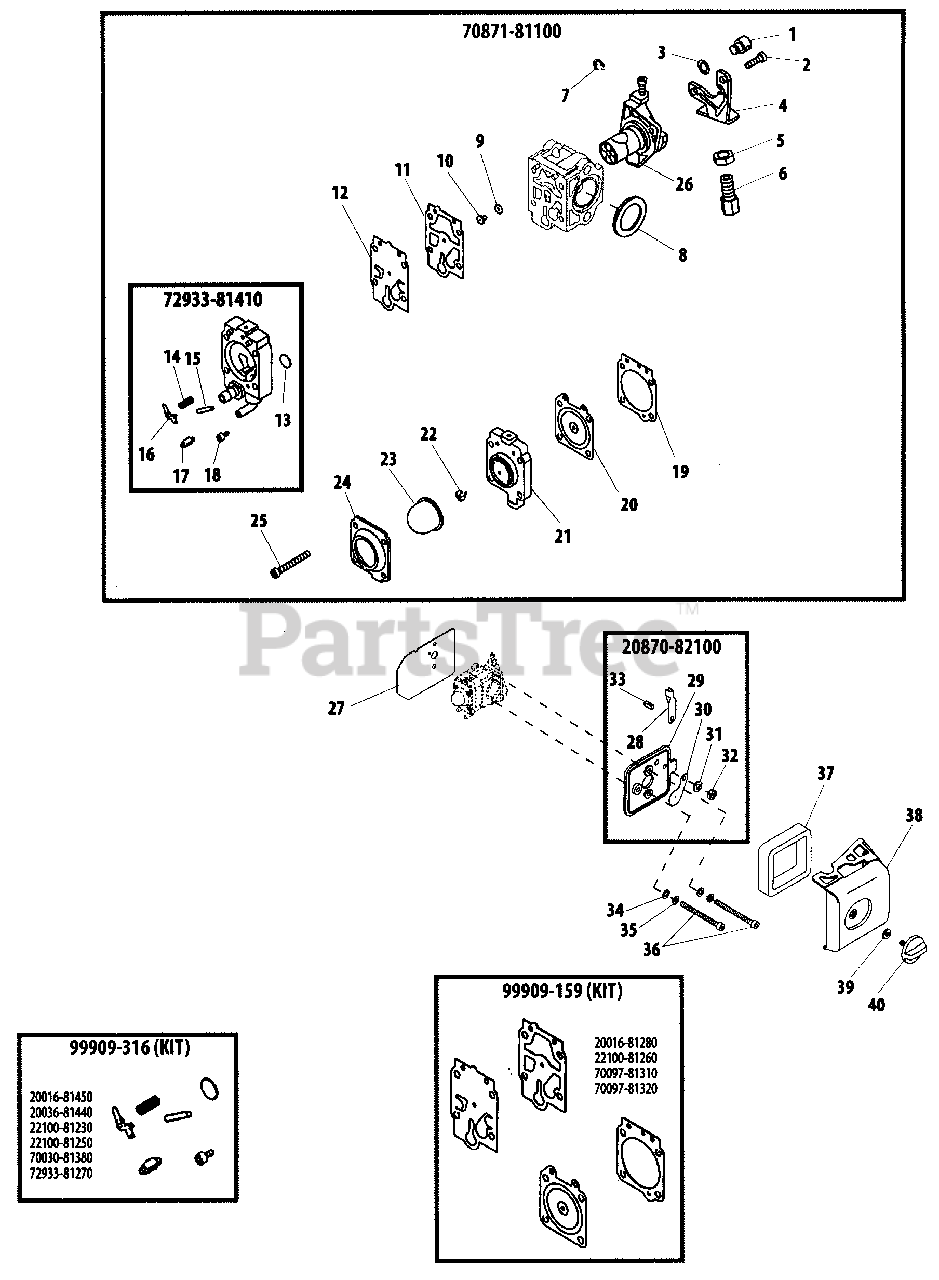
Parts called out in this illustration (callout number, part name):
1	SWIVEL
2	SCREW
3	WASHER
4	BRACKET, CABLE
5	NUT
6	NUT, CABLE ADJUST
7	RING, RETAINING
8	SEAL
9	O-RING
10	JET
11	GASKET, PUMP
12	DIAPHRAGM, PUMP
13	STRAINER
14	SPRING, METERING LEVER
15	PIN, METERING LEVER
16	LEVER, METERING
17	VALVE, INLET NEEDLE
18	SCREW, METERING LEVER PIN
19	GASKET, METERING
20	DIAPHRAGM, METERING
21	BASE, PURGE
22	VALVE, CHECK
23	BULB, PURGE
24	RETAINER, PURGE BULB
25	SCREW, PUMP COVER
26	THROTTLE VALVE ASSY
27	GASKET
28	LEVER, CHOKE
29	CASE, AIR FILTER
30	PLATE, CHOKE
31	LOCKWASHER - 6
32	NUT - 6
33	SHAFT, CHOKE
34	WASHER - 5
35	LOCKWASHER - 5
36	SCREW - 5X60
37	FILTER, AIR
38	COVER, AIR FILTER
39	WASHER - VINYL
40	THUMBSCREW
20870-82100	AIR FILTER CASE ASSY
70871-81100	CARBURETOR
72933-81410	BASE, PURGE
99909-159	DIAPHRAGM/GASKET KIT
99909-316	REPAIR KIT
